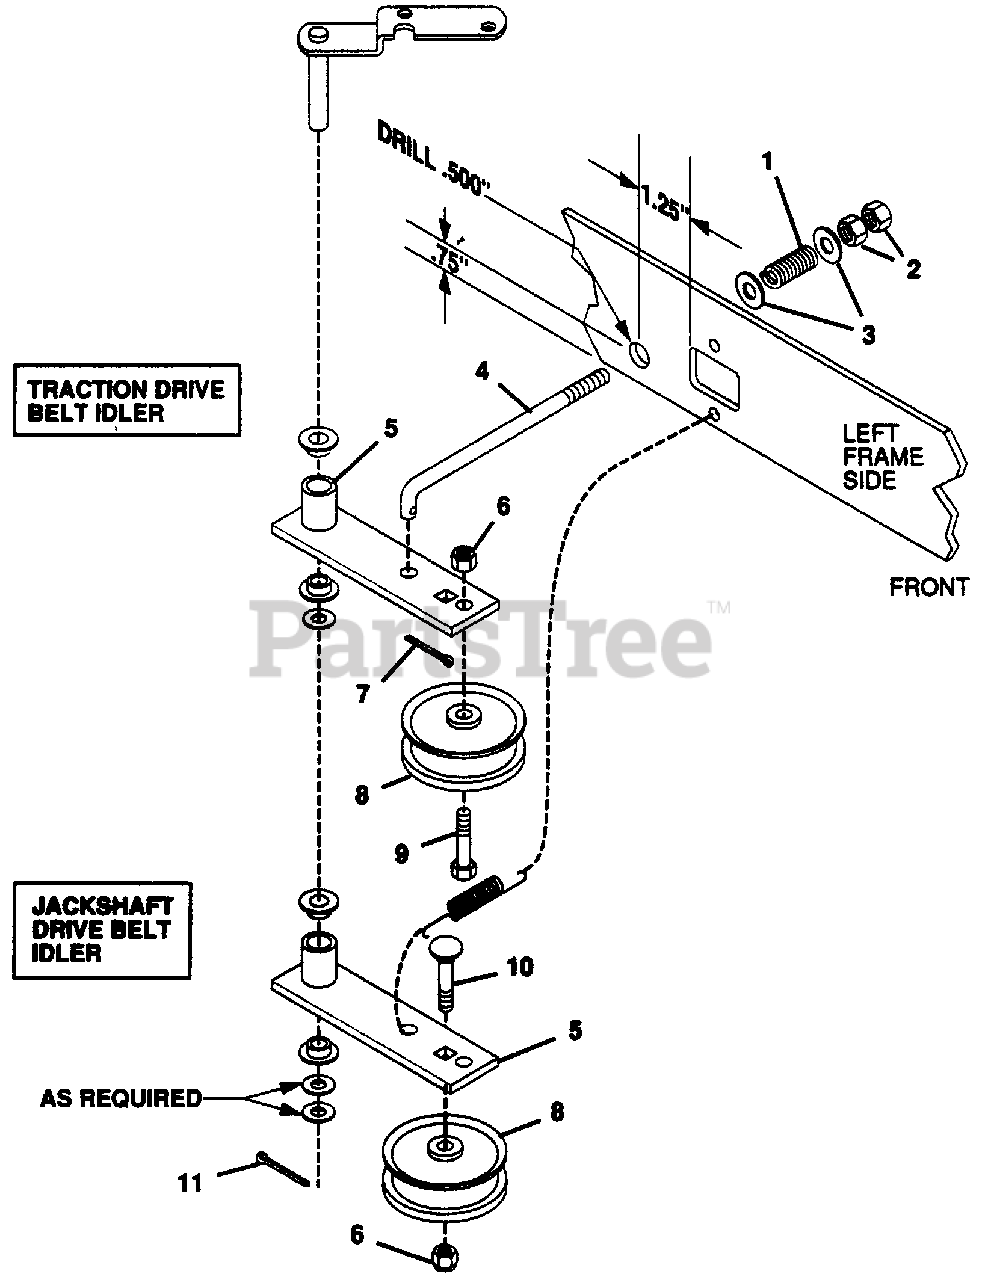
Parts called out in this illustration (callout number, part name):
1	Spring, Comp. 1X.78X338 Lb/In
2	Nut, Hex 3/8-16
3	Washer, Flat .406x.812x.065
4	Rod, Idler
5	Weldment, Idler Arm
6	Nut, Lock 3/8-16
7	Pin, Cotter .094x1.00
8	Idler
9	Bolt, Hex 3/8-16x1.75
10	Bolt, 3/8-16x1.75 Rd.Hd.Sq.Nk.
11	Pin, Cotter .125x1.25
